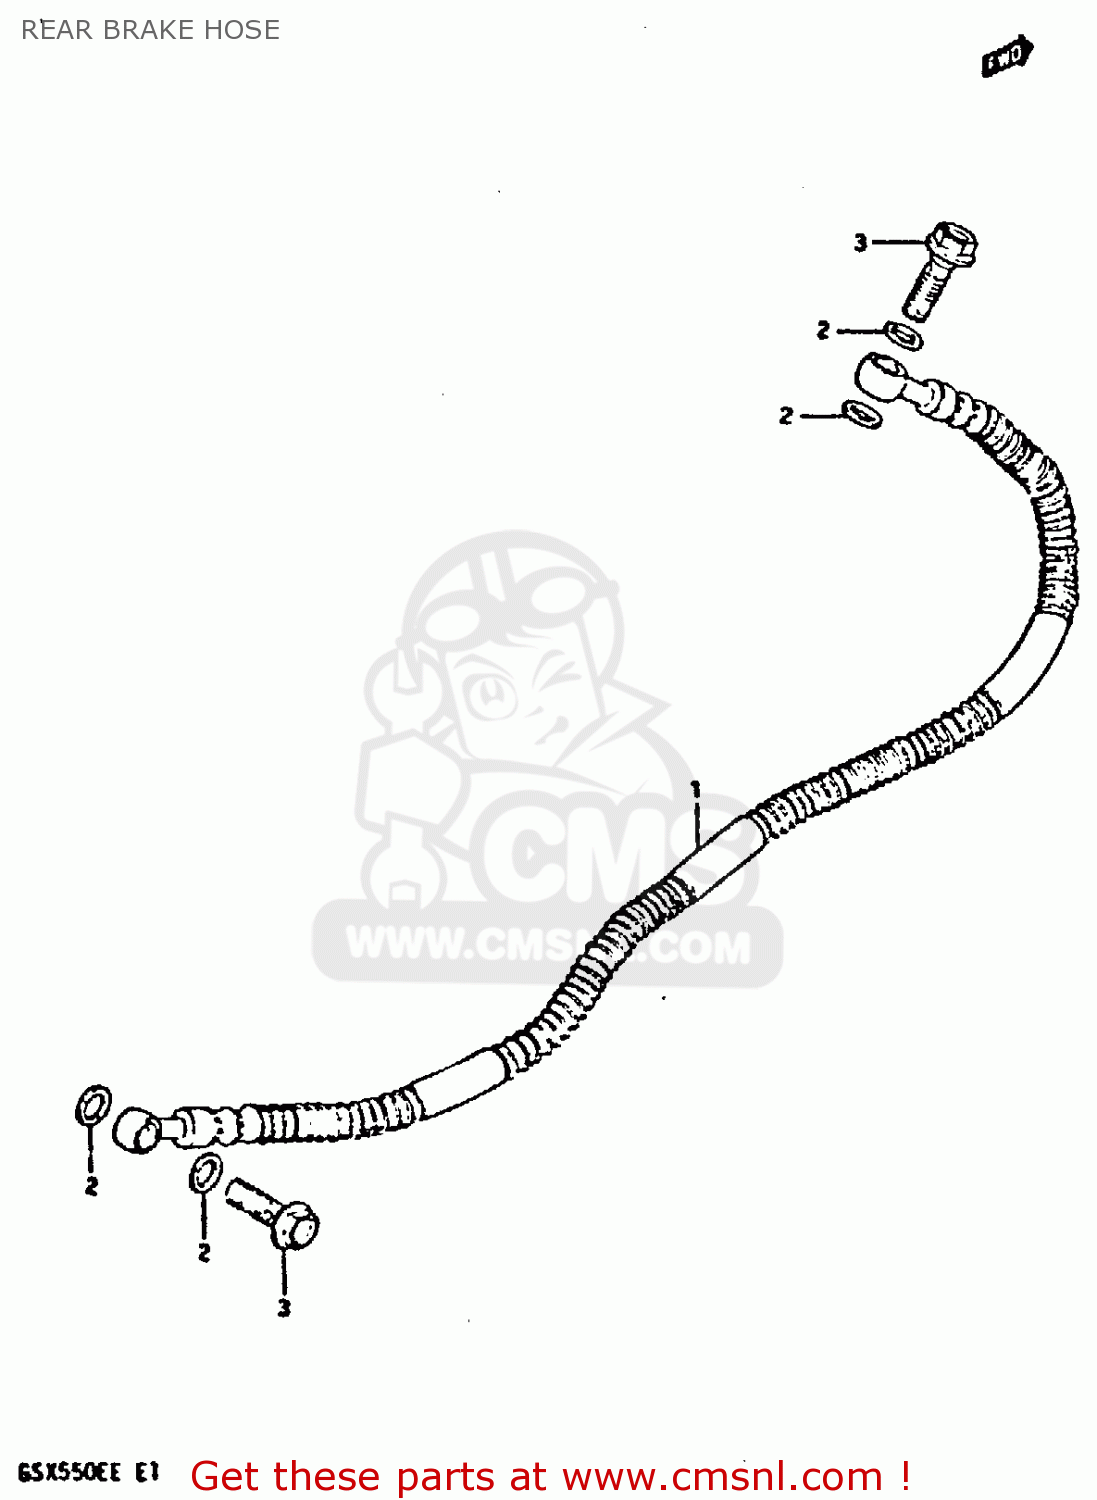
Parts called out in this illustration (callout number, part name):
1	HOSE,REAR BRAKE
2	WASHER
3	BOLT UNION
